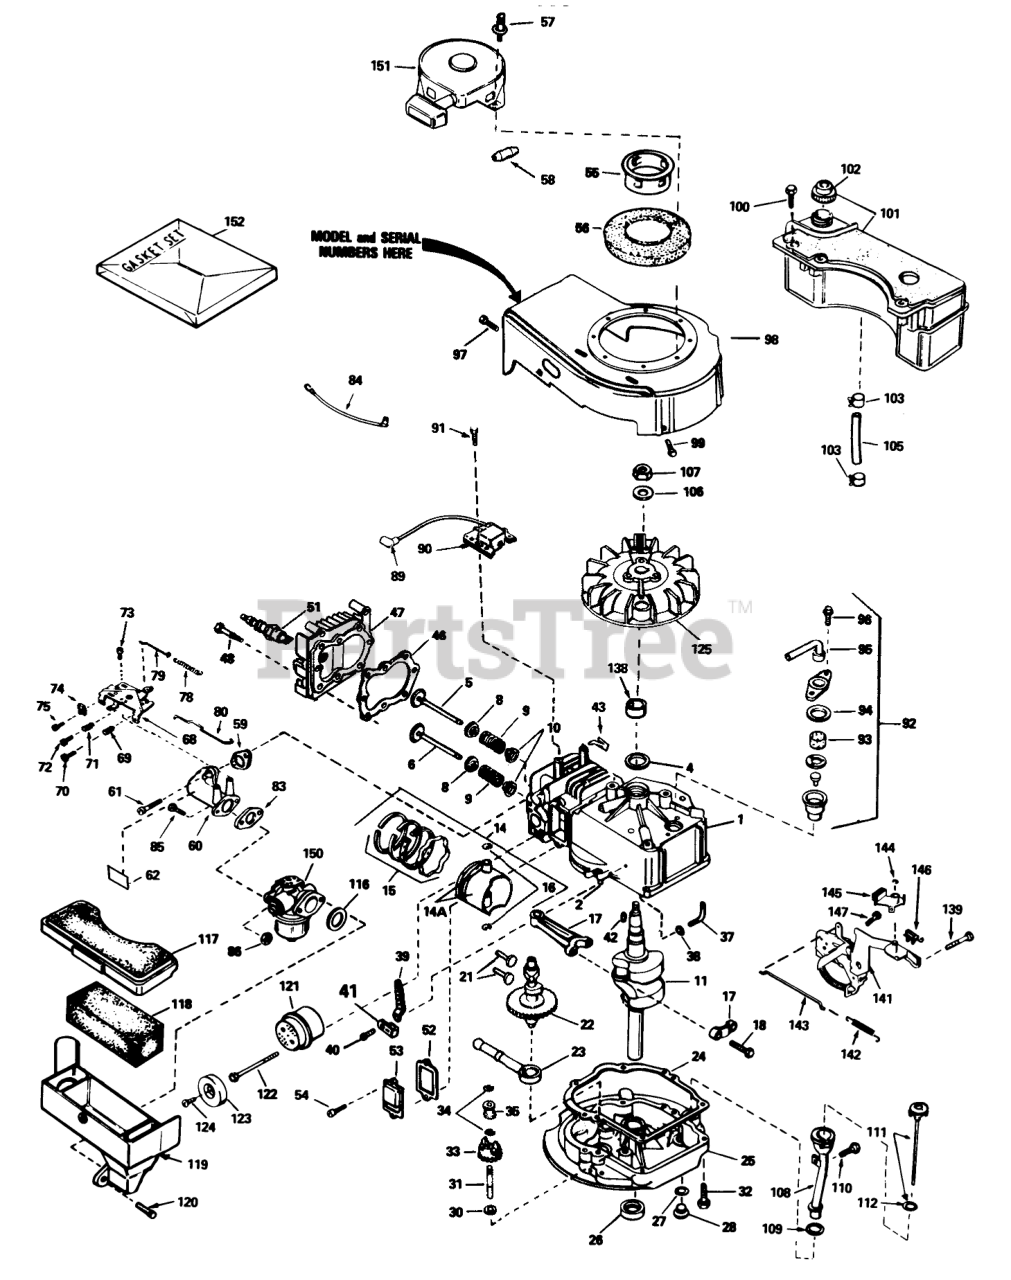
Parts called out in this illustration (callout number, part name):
1	Cylinder Assy. (Incl. #2 & 4)
2	Pin-Dowel
4	Seal-Oil
5	Valve-Intake (Std.)(Incl. #10)
5	Valve-Intake (1/32" Oversize)(Incl. #10)
6	Valve-Exhaust (Std.)(Incl. #10)
6	Valve-Exhaust (1/32" Oversize)(Incl. #10)
8	Cap-Upper Valve Spring
9	Spring-Valve
10	Cap-Valve, Spring
11	Crankshaft
14	Piston-Pin & Ring Assy. (Std.)(Incl. #14A, 15 & 16)
14	Piston-Pin & Ring Assy. (.010 Oversize)(Incl. #14A, 15 & 16)
14	Piston-Pin & Ring Assy. (.020 Oversize)(Incl. #14A, 15 & 16)
14A	Piston & Pin Assy. (Std.)(Incl. #16)
14A	Piston & Pin Assy. (.010 Oversize)(Incl. #16)
14A	Piston & Pin Assy. (.020 Oversize)(Incl. #16)
15	Piston Ring Set Std.
15	Piston Ring Set .010 O.S.
15	Piston Ring Set .020 O.S.
16	Ring-Retaining, Piston Pin
17	Rod Assy.-Connecting (Incl. #18)
18	Bolt-Rod, Connecting
21	Lifter-Valve
22	Camshaft(Mech.Comp. Release)
23	Oil Pump ASM
24	Gasket, Mounting
25	Flange Assy.-Mounting (Incl. #26, 27, 28 & 31)
26	Seal Oil
27	Gasket-Oil Drain
28	Plug Oil Drain
30	Washer-Flat
31	Shaft-Governor
32	Screw (1/4-20 x 1-1/4)
33	Gear Assy.-Governor (Incl. #30)
34	Ring-Retaining
35	Spool-Governor
37	Rod-Governor (Incl. #38)
38	Washer-Flat
39	Governor Lever
40	Screw
41	Clamp-Lever, Governor
42	Key-Flywheel
43	Clip-Wire
46	Gasket-Cylinder Head
47	2025A67 ADD.ASSEMBL
48	Screw (5/16-18x1-1/2)
51	Plug, Spark (Autolite 458, Champion J-19LM or equiv.)
52	Gasket-Breather
53	Cover-Valve
55	Cup-Starter
56	Screen-Starter
57	Pop Rivet (Can be purchased locally)
58	Retainer-Starter Rope
59	Gasket-Intake
60	Pipe-Intake (Incl. #59)
61	Screw (1/4-20 x 1)
62	Decal-Primer
68	A Control Assy.-Remote Speed (Incl. #69-72)
69	61709/GIL1515A/95-5
70	Screw
71	Spring-Compression
72	Screw
73	Screw (10-24 x 9/16)
74	Conduit
75	Screw (10-32 x 3/8)
78	Spring Governor
79	2035A67 ADD.ASSEMBL
80	Link-Throttle
83	Gasket
84	Ground Wire
85	Screw (1/4-28 x 7/8)
86	Nut and Lock Washer (1/4-28)
89	Cover-Spark Plug
90	Lamination & Coil Assy. (Solid State)(Incl. #89)
91	Screw
92	Breather Assy. (Incl. #93-96)
93	Element-Breather
94	Gasket-Breather
95	Tube, Breaker
96	Screw (10-24 x 9/16)
97	Screw (10-24 x 9/16)
98	Housing-Blower
99	Screw (1/4-20 x 1/2)
100	Screw (10-32 x 35/64)
101	Tank Assy.-Fuel (Incl. #102)
102	Cap-Fuel
103	Clamp-Line, Fuel
105	Line-Fuel
106	Washer-Belleville
107	Nut-Flywheel
108	Tube-Oil Fill
110	Screw (10-32 x 1/2)
111	Dipstick-Oil (Incl. #112)
116	Gasket-Cleaner, Air
117	Cover Air Cleaner
118	Filter-Air Cleaner
119	Body Air cleaner
121	Muffler (Incl. #122)
123	Cover-Muffler
124	Screw
125	Flywheel
139	Screw (1/4-20 x 3/8)
141	Bracket Assy.
142	Spring-Extension
143	Link-Control
144	Ring-Retaining
145	Lever-Brake
146	Terminal
147	Screw-Hex. Hd.
150	Carburetor (Incl. #83)
151	tarter-Rewind
152	Gasket Set
